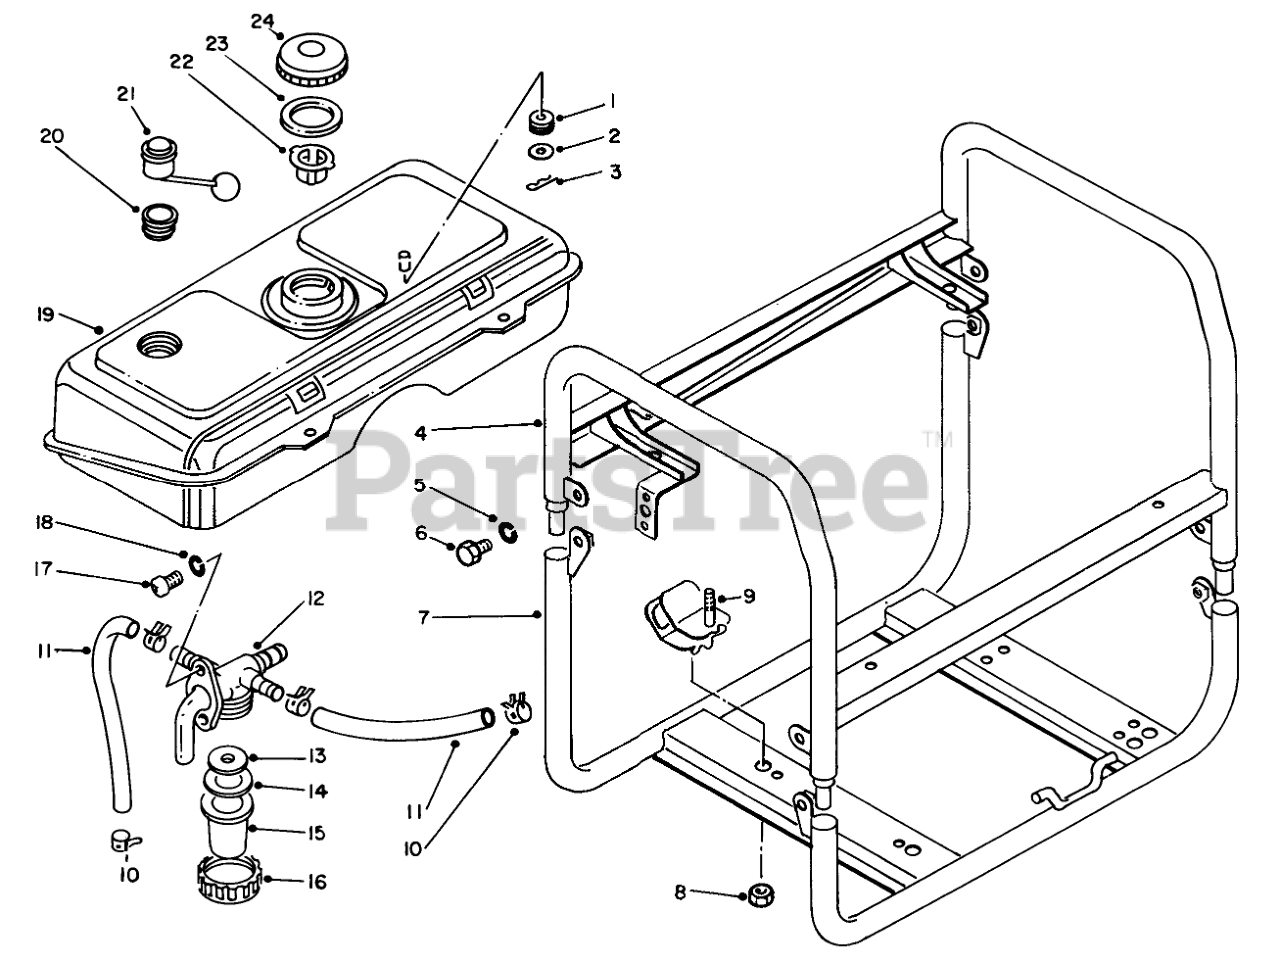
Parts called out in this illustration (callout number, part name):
1	CUSHION
2	WASHER
4	Frame-Upper
5	WASHER-LOCK
7	Screw
9	Mount-Engine
12	Cock Assembly-Fuel (Incl. Ref. #13-16)
13	FILTER
14	GASKET
17	Screw
18	Lockwasher
19	Tank-Fuel
20	Gasket
21	Gauge Assembly-Fuel (Incl. Ref. #20)
22	FILTER
23	GASKET
24	Cap (Incl. Ref. #23)
